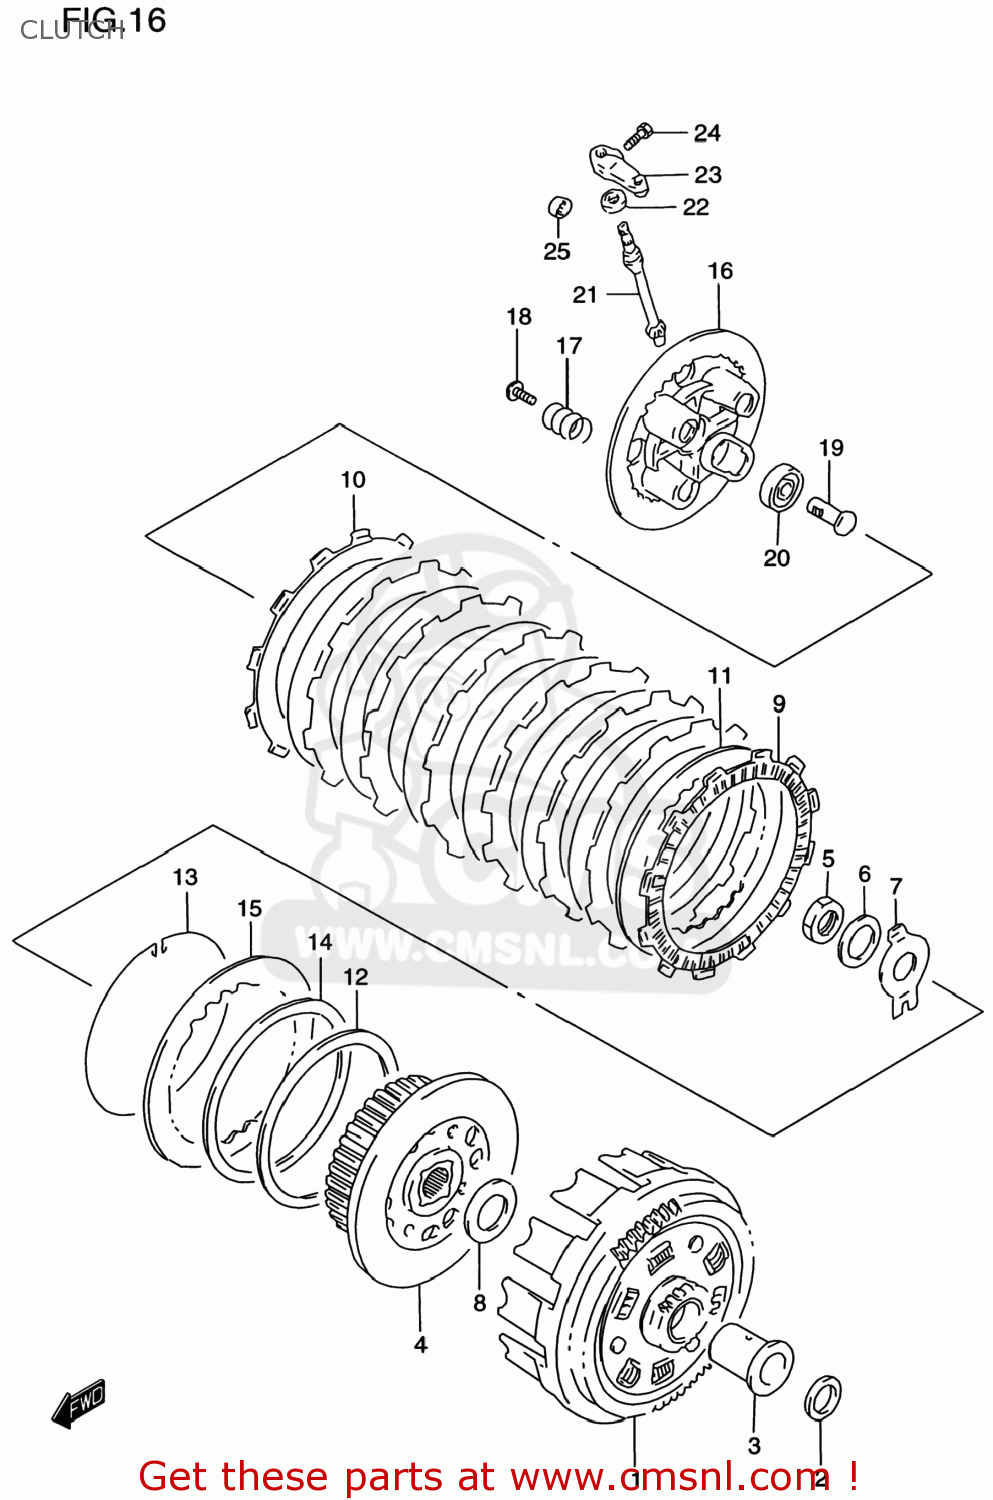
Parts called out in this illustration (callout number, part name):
1	GEAR ASSEMBLY,PRIMARY DRIVE
2	WASHER(22X32X3)
3	SPACER,PRIMARY DRIVEN GEAR
4	HUB,CLUTCH SLEEVE
5	NUT
6	WASHER
7	WASHER
8	WASHER(22X44X2)
9	PLATE,CLUTCH DRIVE (NAS)
10	PLATE,CLUTCH DRIVE (NAS)
11	PLATE,CLUTCH DRIVEN NO.1 (NAS)
12	SEAT,WAVE WASHER
13	RING,STOPPER
14	WASHER
15	PLATE,CLUTCH DRIVEN (NAS)
16	DISC,CLUTCH PRESSURE
17	SPRING
18	BOLT(6X16)
19	RACK,CLUTCH RELEASE
20	BEARING
21	PINION,CLUTCH RELEASE
22	SEAL,OIL(10X17X5)
23	ARM,CLUTCH RELEASE
24	BOLT
25	BEARING(12X16X10)
